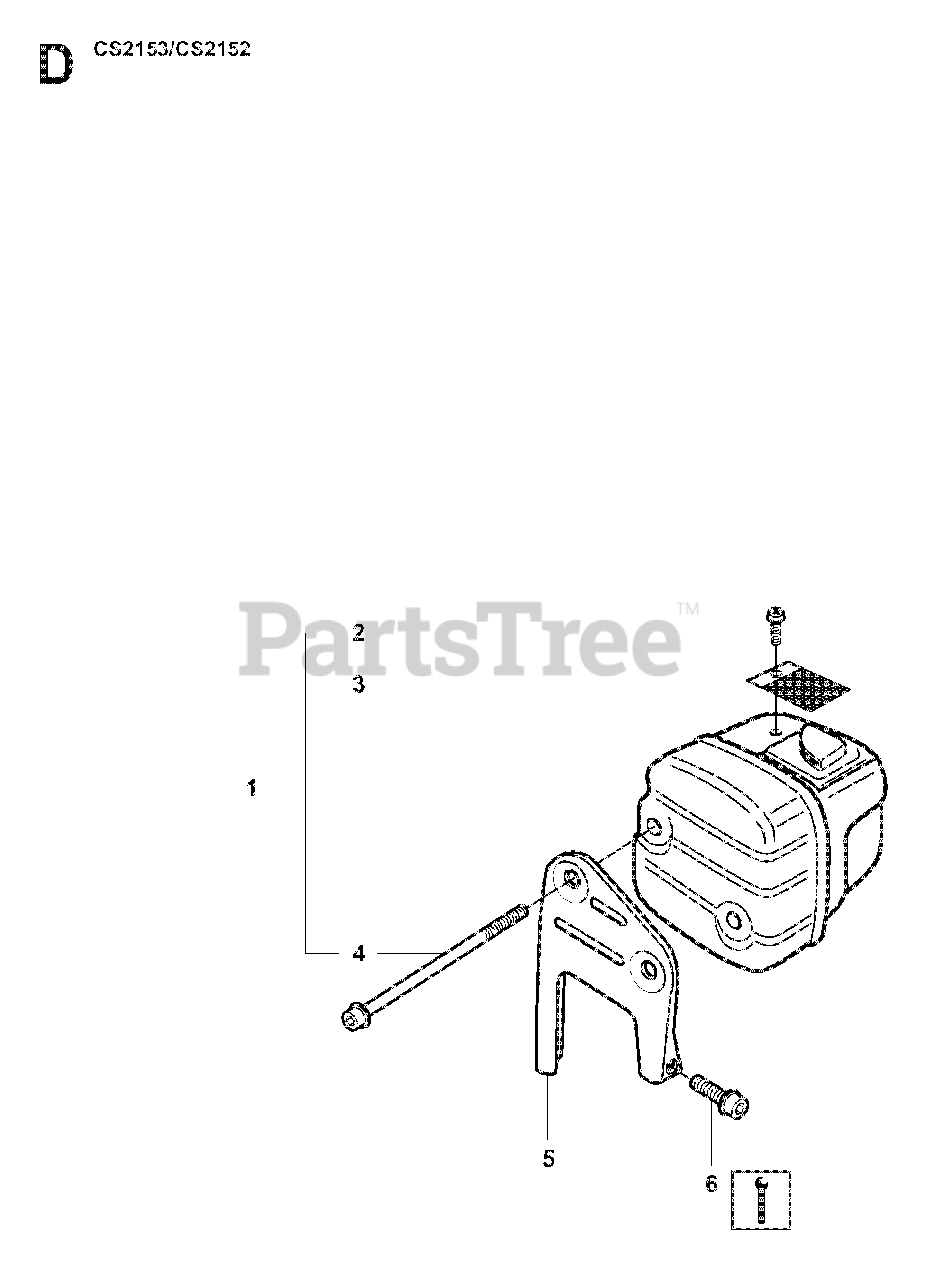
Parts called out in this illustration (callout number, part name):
1	MUFFLER
3	RP SCREEN
5	SUPPORT
